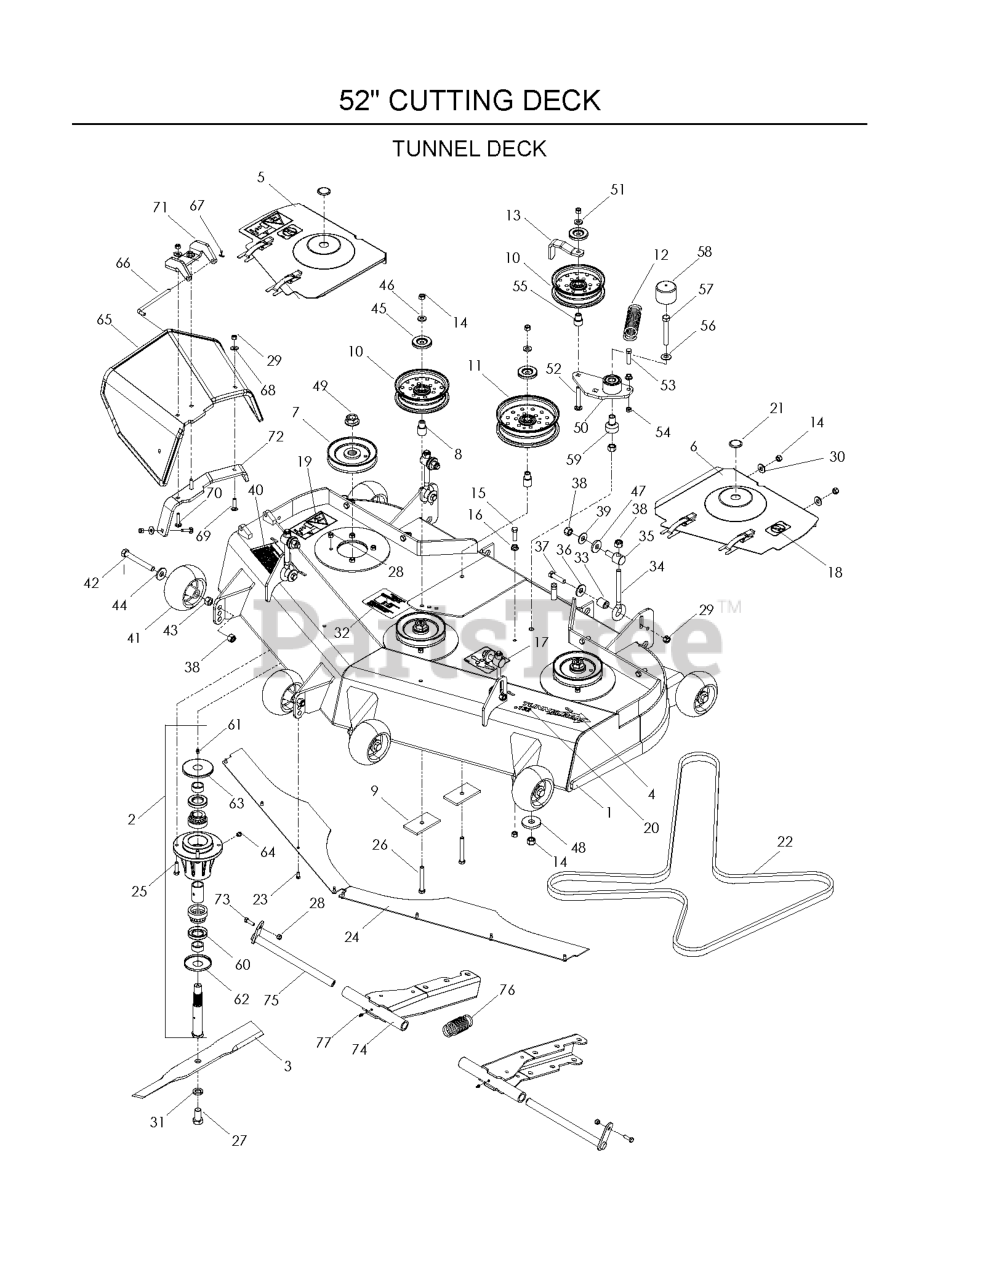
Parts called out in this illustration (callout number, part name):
1	DECK W/DECALS 52" HUS
2	HOUSING ASM, 52/61
3	BLADE, 18"
4	DECAL, TUNNEL RAM 8"
5	BELT SHIELD ASSEMBLY, 52" R.H.
6	BELT SHIELD ASSEMBLY, 52" L.H.
7	PULLEY - 52"
8	IDLER BUSHING
9	SUPPORT PLATE
10	IDLER PULLEY
11	PULLEY - IDLER, 6IN WIDE
13	GUIDE, BELT
14	NUT 3/8-16 NYLOC
15	HCS 3/8C X 1 1/4 GR5
16	NUT 3/8C WHIZ
17	DECAL, BELT ROUTING
18	DECAL, NO STEP
19	DECAL, EURO SEVERING
20	DECAL, 132
21	BUTTON PLUG - 1" NOM.
22	BELT, DECK
23	HEX CAP SCREW 1/4
24	52" CONFINEMENT PLATE
25	HCS 5/16C X 1 1/4
26	HCS 3/8C X 3
27	HCS 5/8F X 1 1/4
28	NUT 5/16 NYLOC
29	NUT 7/16C CENTERLOCK
30	WASHER 3/8 FLAT
31	LOCKWASHER 5/8
32	DECAL, ANTI SCALP
35	SWIVEL, DECK HEIGHT ADJ
36	SPRING WASHER - .50
37	HCS 7/16 - 14 X 1 3/4
38	NUT 1/2-13 HEX NYLOC ZD
39	WASHER 1/2 FLAT
40	DECAL, DISCHARGE, MULTILINGUAL
41	GAUGE WHEEL
42	HCS 1/2-13 X 4 GR 5 ZD
43	NUT HEX 1/2
44	WASH USS FLAT 1/2
45	DUST SHIELD
46	WASHER, 3/8 THICK
47	WASHER-.533IDX1.37OD
48	WASHER, SUPPORT
49	NUT FLANGE 3/4-16
50	ARM-IDLER W/BRG
51	WASHER, 3/8 THICK
52	RHSNB 3/8-16 X 2.75
53	HCS 3/8-16 X 1-1/2
54	NUT 3/8-16 HEX JAM
55	BUSHING, IDLER
56	CONTACT BELLSPR 1/2
57	HCS 1/2C X 3 1/4
58	CAP, VINYL
59	PIVOT, BEARING
60	SHAFT SEAL
62	BOTTOM DUST CAP
63	TOP DUST CAP
64	PLUG-VENTED
65	CHUTE, RUBBER DISCHARGE 52/61"
66	PIN, CHUTE PIVOT
67	RP_COTTER PIN 1/8 X 3/4
68	WASHER 5/16 FLAT
69	BOLT, CARRIAGE 5/16X1-1/4
70	RHSNB 5/16-18 X 1-1/2 GR 5 ZD
71	PIVOT BRACKET - RUBBER CHUTE
72	BRACKET, REINF-CHUTE
73	HCS 5/16C X 1
74	STRUT WELDMENT, TRD
76	DECK LIFT SPRING
77	ZERK
